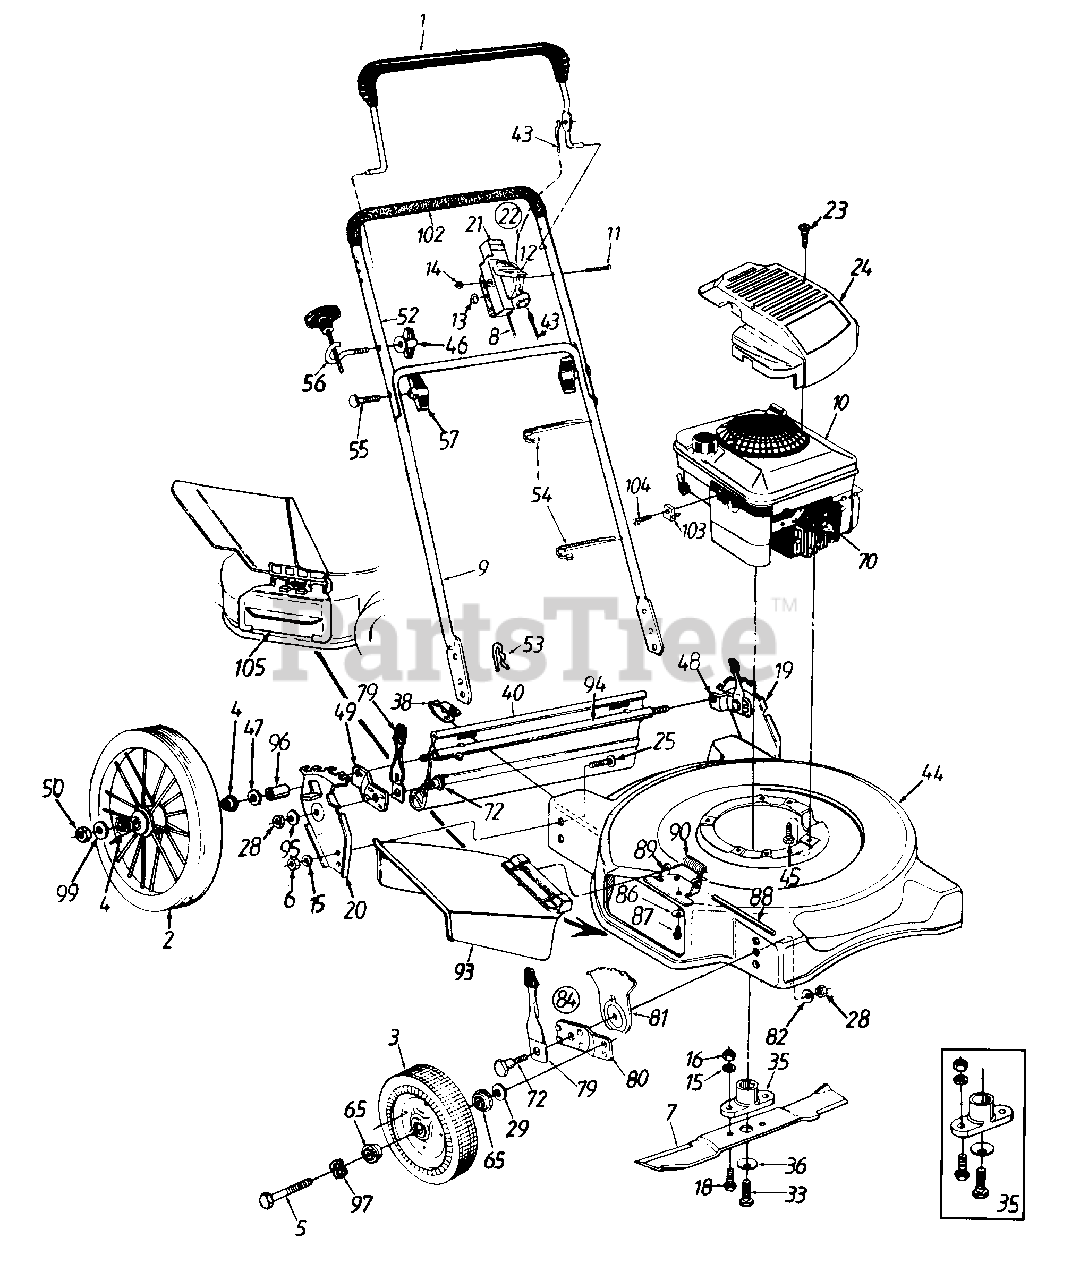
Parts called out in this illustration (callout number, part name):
1	Control Handle
2	16" Wheel Ass'y.
3	Front Wheel Ass'y.
4	Bearing 1/2" I.D.
5	Front Axle Bolt
6	Hex Nut 3/8-24 Thd. (Gr. 8)
7	22" Blade
7	22" Mulching Blade
8	Throttle Control Wire - 51"
10	Engine
11	Oval C-Sunk Mach. Scr.
12	Throttle Lever
13	Spr. Wash. .66" I.D.
14	Hex L-Nut 1/4-20 Thd.
15	L-Wash. 3/8" I.D.
16	Hex Nut 3/8-24 Thd.
17	Flange L-Nut 3/8-18 Thd.
18	Hex Bolt 3/8-24 x 1.0" Lg.
19	Handle Brkt. Ass'y. - L.H.
22	Throttle Box Comp.
23	Hi-Lo Scr. #10 x 1.25" Lg.
25	Ribbed Neck Bolt 3/8-24 x .80"
28	Hex Nut 3/8-16 Thd.
29	Bell-Wash..400" I.D. x .88"
33	Hex Bolt 3/8-24 x 1.5" Lg.
35	Blade Adapter Kit
36	Bell-Wash. .39" I.D.
38	Hinge Clip
40	Rear Flap Ass'y.
43	Control Cable - 39"
46	Handle Knob 1/4-20 Thd.
47	Wave Wash. .51" I.D.
48	Small Pivot Bar - L.H.
49	Small Pivot Bar - R.H.
50	Hex Jam Nut 3/8-16 Thd.
52	Upper Handle
53	Intern. Cot. Pin 5/16" Dia.
54	Cable Tie
55	Curved Hd. Bolt 5/16-18 x 2" Lg.
56	Rope Guide
57	Hand Knob
65	Bearing
70	Spark Plug Boot
72	Shoulder Bolt .50" Dia.
79	Spring Lever Ass'y. w/Knob
81	Height Adj. Plate
82	Bell-Wash. .39" I.D. x 1.38"
84	Front Height Adj. Ass'y. Comp. - R.H.
86	Bell-Wash. .285" I.D. x .75"
87	Hex Wash. Hd. Tap Scr. 1/4-20 x .5" Lg.
88	Hinge Pin
89	Adapter Plate
90	Torsion Spring
93	Chute Deflector Ass'y. Comp.
94	Rear Axle
95	Bell-Wash. .39" I.D. x 1.13"
96	Spacer .55" I.D. x .75"
97	Wave Washer .51" I.D.
99	FL-Wash. .406" I.D. x .81"
100	Spr. Wash. .5" I.D. x 1.0"
102	Foam Grip
103	Casing Clamp
104	Hex Wash. Hd. Tap Scr. #10-32 x .62" Lg.
105	Mulching Baffle
